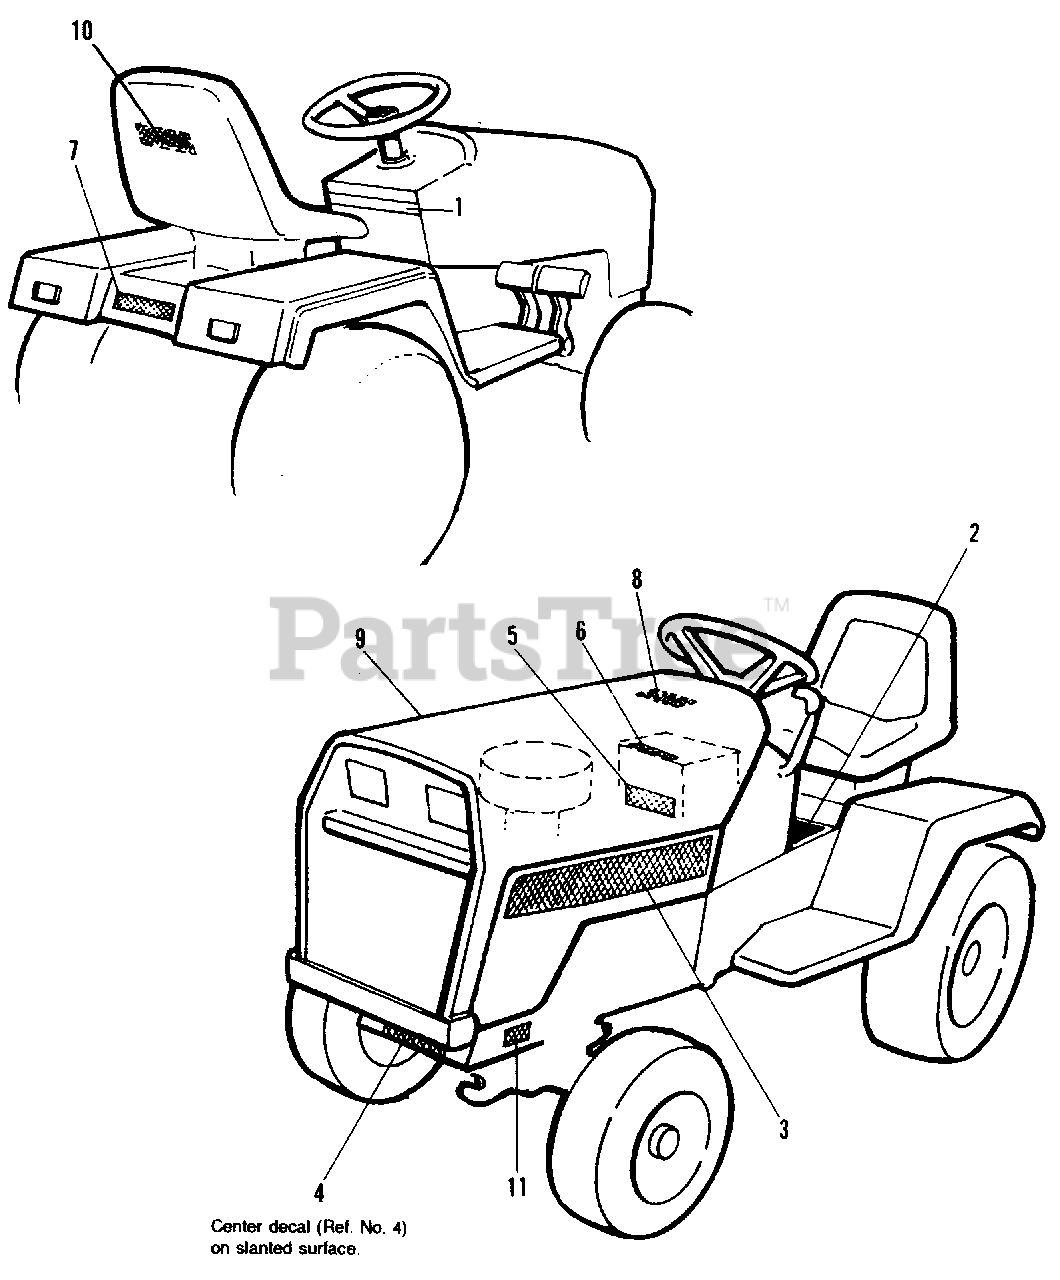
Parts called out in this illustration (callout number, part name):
1	DECAL, Panel, Rear Dash (Choke, Ignition, etc.
1	DECAL, Panel, Rear Dash (Choke, Ignition, etc.)
2	DECAL, Tunnel Cover (18 H.P. only)
2	DECAL Tunnel Cover (20 H.P. only)
3	DECAL, Hood, L.H. (18 H.P. only)
3	DECAL, Hood, L.H. (20 H.P. only)
4	DECAL, Warning, Front PTO Shield
5	DECAL, Battery
6	DECAL, Warning (Disconnect Elect. Ground, etc.)
7	DECAL Rear Logo
7	DECAL, Rear Logo
8	DECAL, Touch up Paint
9	DECAL, Hood, R.H. (18 H.P. only)
9	DECAL, Hood, R.H. (20 H.P. only)
10	DECAL, USA Logo
11	I.D. PLATE
12	DECAL, Hub Cap
